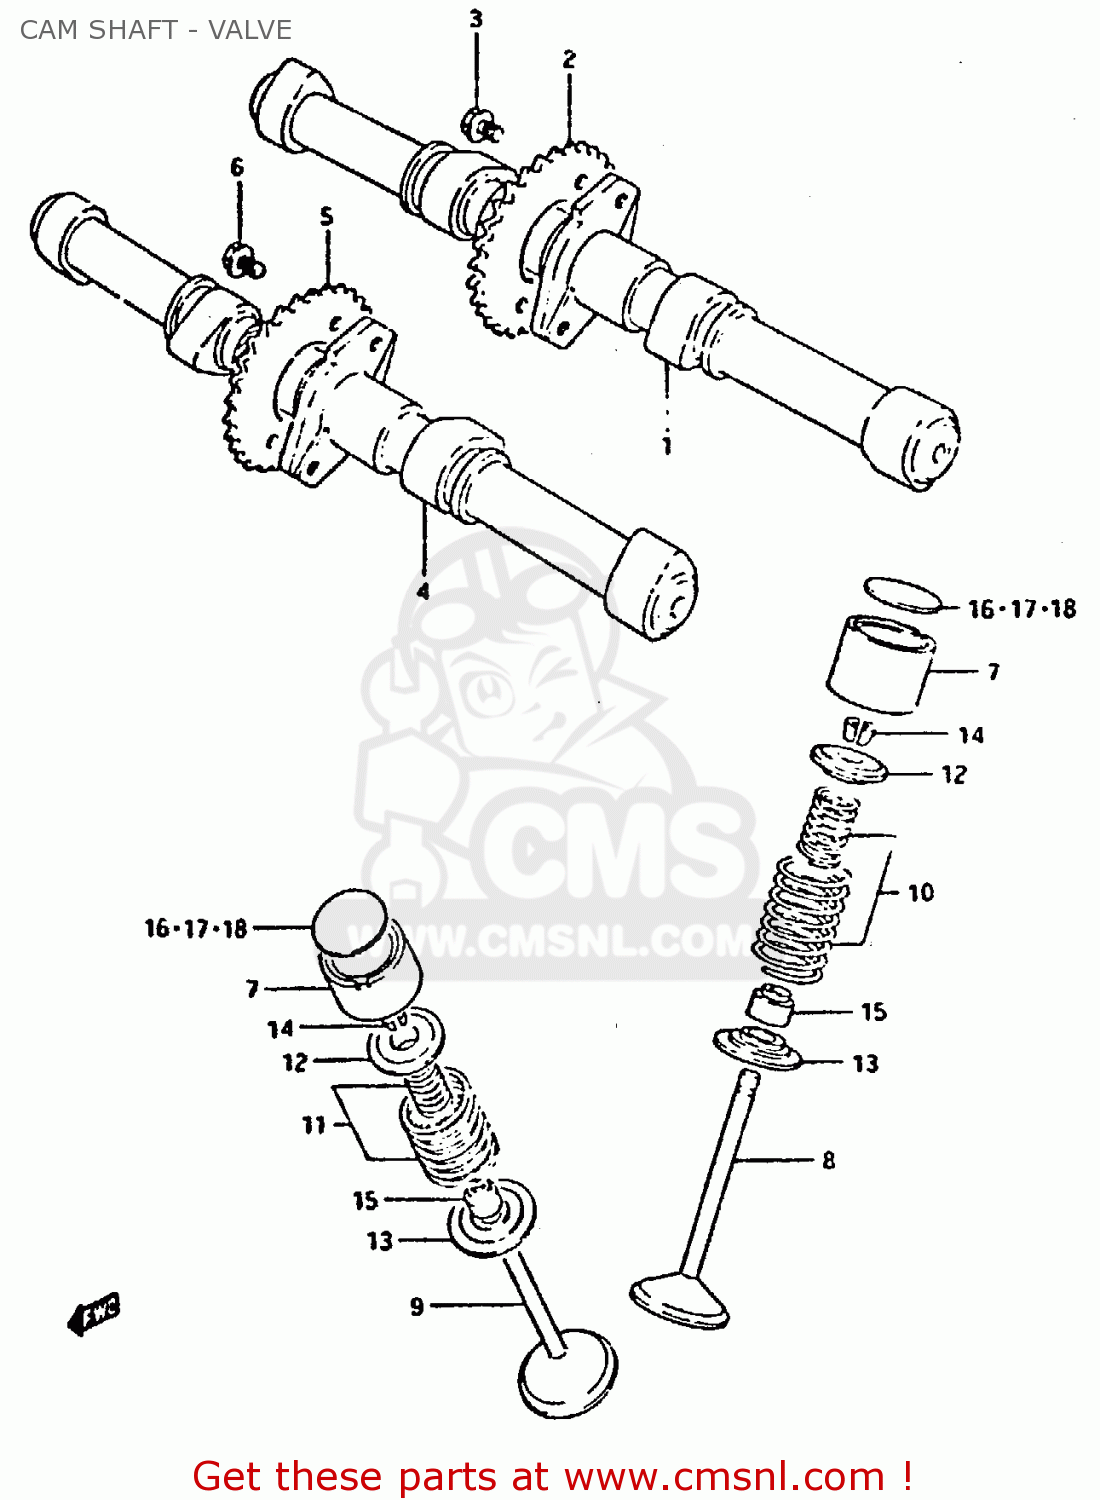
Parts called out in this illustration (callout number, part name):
1	CAMSHAFT,INTAKE
2	SPROCKET,INTAKE CAMSHAFT
3	BOLT(7X11)
4	CAMSHAFT,EXHAUST
5	SPROCKET,EXHAUST CAMSHAFT
6	BOLT(7X11)
7	TAPPET
8	VALVE,INTAKE
9	VALVE,EXHAUST
10	SPRING SET,VALVE
11	SPRING SET,EXHAUST VALVE
12	RETAINER,VALVE SPRING
13	SEAT,VALVE SPRING
14	COTTER VALVE
15	SEAL,OIL(7X14.4X9)
16	SHIM,TAPPET
17	SHIM,TAPPET
18	SHIM,TAPPET
